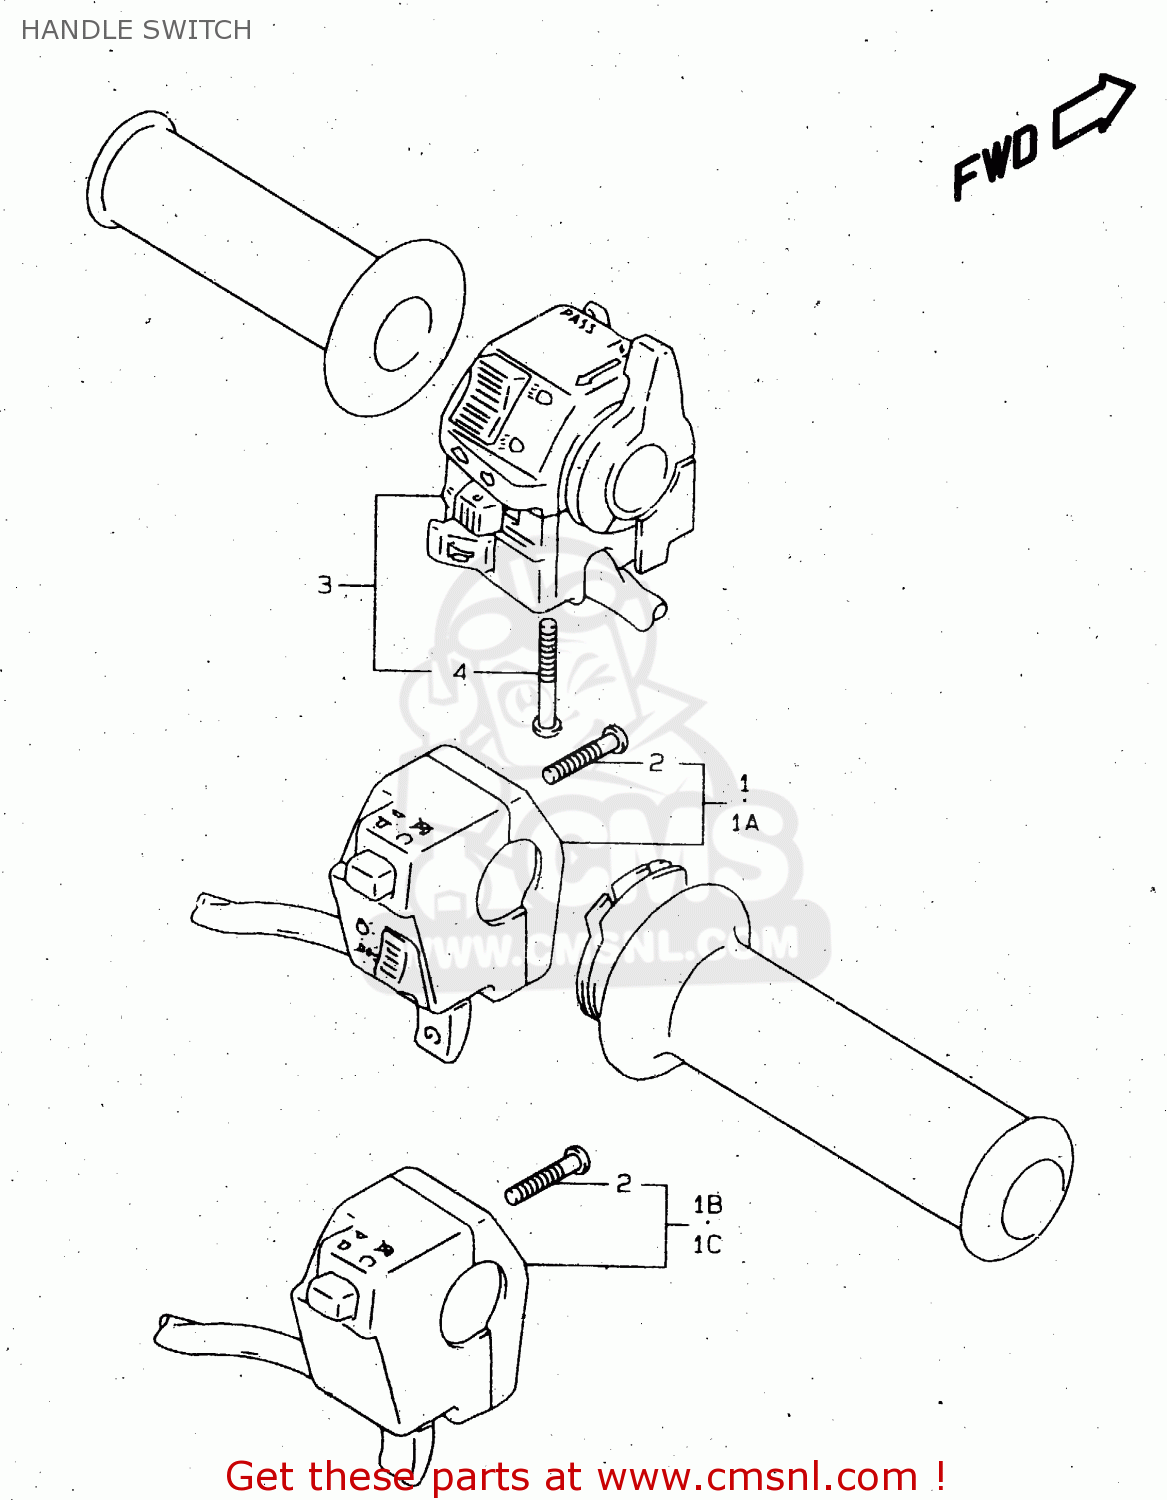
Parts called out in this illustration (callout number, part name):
1	SWITCH ASSY,HANDLE,R
1A	SWITCH ASSY,HANDLE,R
1B	SWITCH ASSY,HANDLE,R
1C	SWITCH ASSY,HANDLE,R
2	SCREW(5X25)
3	SWITCH ASSY,HANDLE,L
4	SCREW, 5X45
